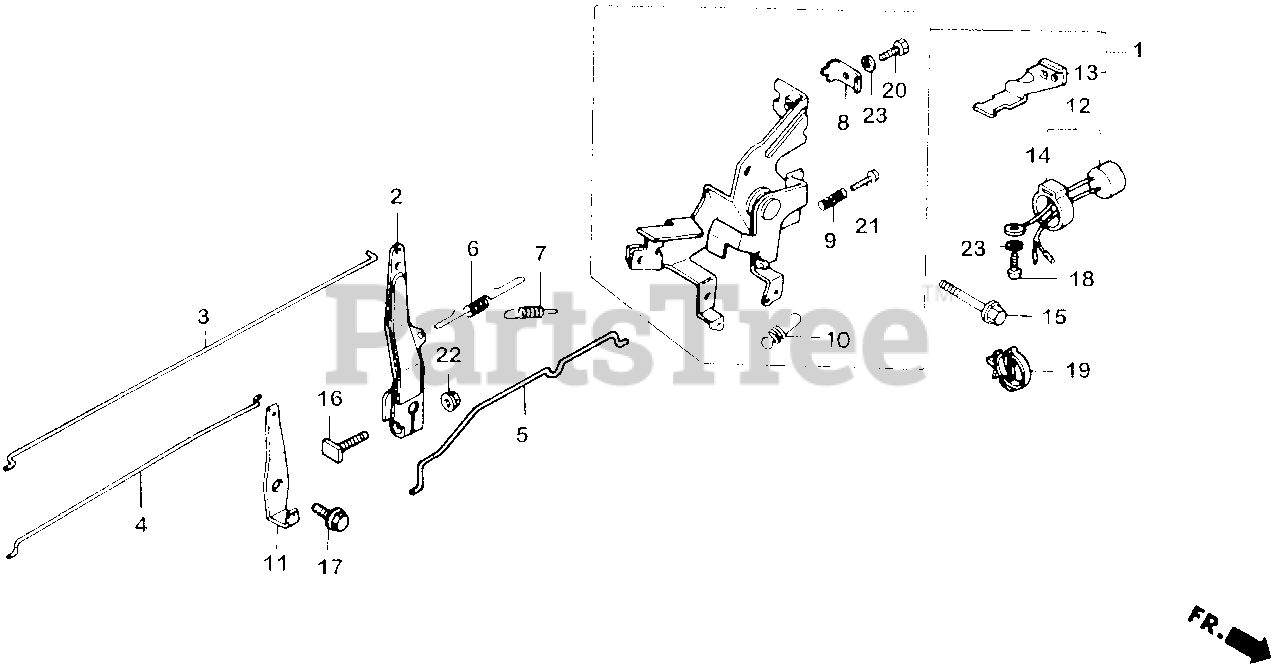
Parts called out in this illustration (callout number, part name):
1	CONTROL ASSY.
2	ARM, GOVERNOR
3	ROD, GOVERNOR
4	ROD, CHOKE
5	ROD, JOINT
6	SPRING, GOVERNOR
7	SPRING, GOVERNOR PRIMARY
8	HOLDER, CABLE
9	SPRING, CONTROL ADJUSTING
10	SPRING, CABLE RETURN
11	LEVER, CHOKE JOINT
12	BUZZER ASSY.
13	STAY, BUZZER
14	SUSPENSION, AUDIBLE PILOT
15	BOLT, FLANGE (6X12) (CT200)
16	BOLT, GOVERNOR ARM
17	BOLT, FLANGE (6MM)
18	SCREW, TAPPING (5X8)
19	CLIP, HARNESS
20	BOLT, RECESSED (5X16)
21	SCREW, PAN (5X20)
22	NUT, FLANGE (6MM)
23	WASHER, SPRING (5MM)
